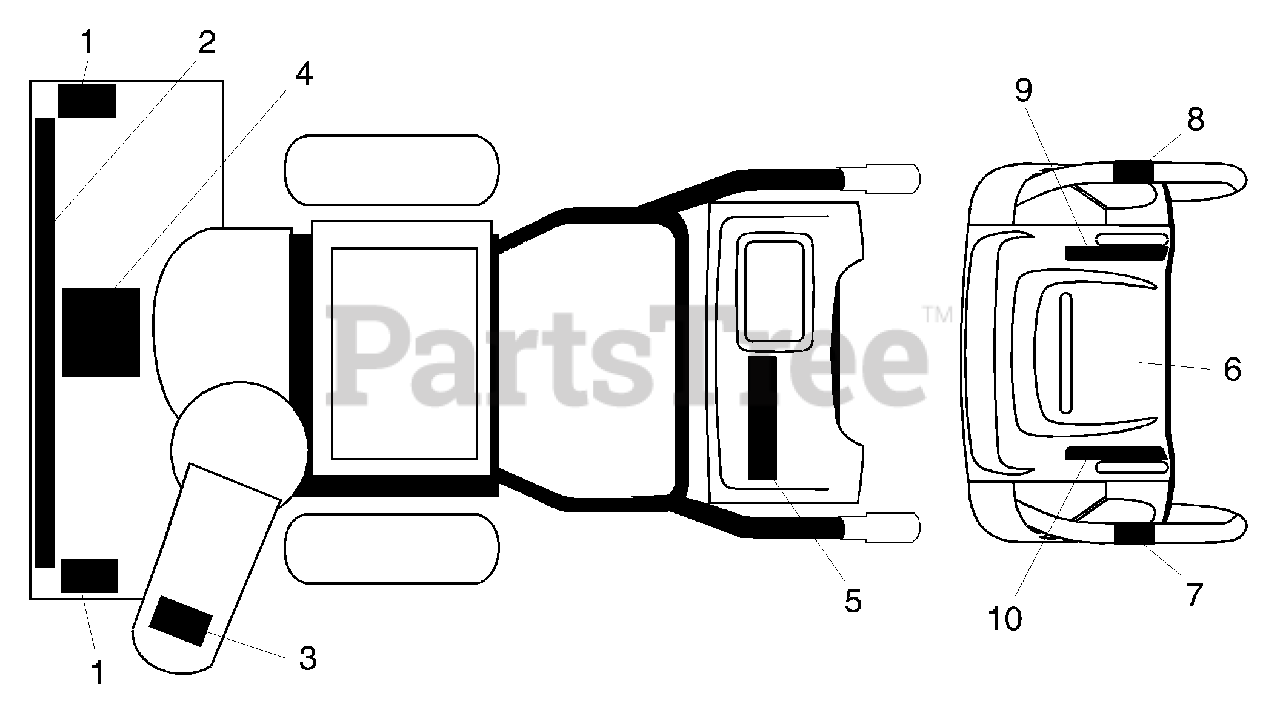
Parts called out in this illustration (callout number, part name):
1	Decal, Danger
2	Decal, Poulan, 5.5HP/24"
3	Decal, Danger, Deflector
4	Decal, Danger
5	Decal, Poulan
6	Decal, Instruction
7	Decal, Traction Lever
8	Decal, Auger Lever
9	Decal, Speed Control
